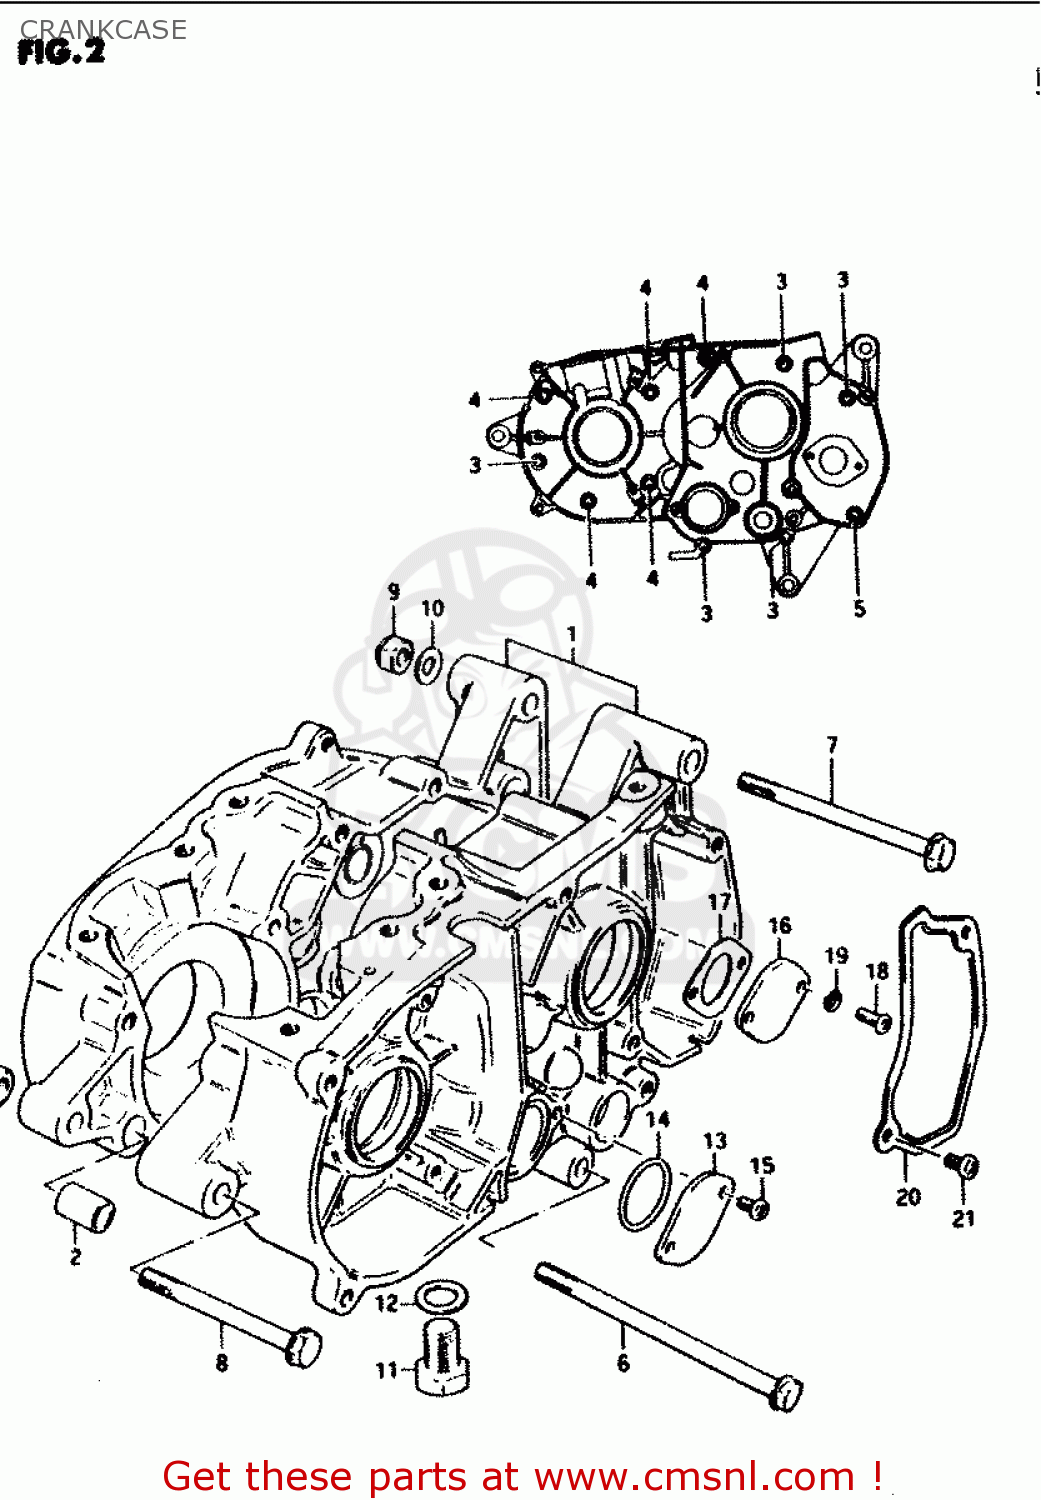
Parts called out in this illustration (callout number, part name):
1	CRANKCASE SET
2	PIN
3	SCREW
4	SCREW
5	SCREW
6	BOLT(8X110)
7	BOLT(8X100)
8	BOLT
9	NUT
10	WASHER
11	BOLT
12	GASKET(10X14X3.6) (NAS)
13	CAP,GEAR SHIFT CAM PIVOT
14	O-RING (D:2.4 ID:26.2)
15	SCREW
16	CAP,OIL PUMP DRIVE SHAFT
17	GASKET,OIL PUMP (NAS)
18	SCREW
19	LOCK WASHER
20	CAP,OIL PUMP INSPECTION
21	SCREW
